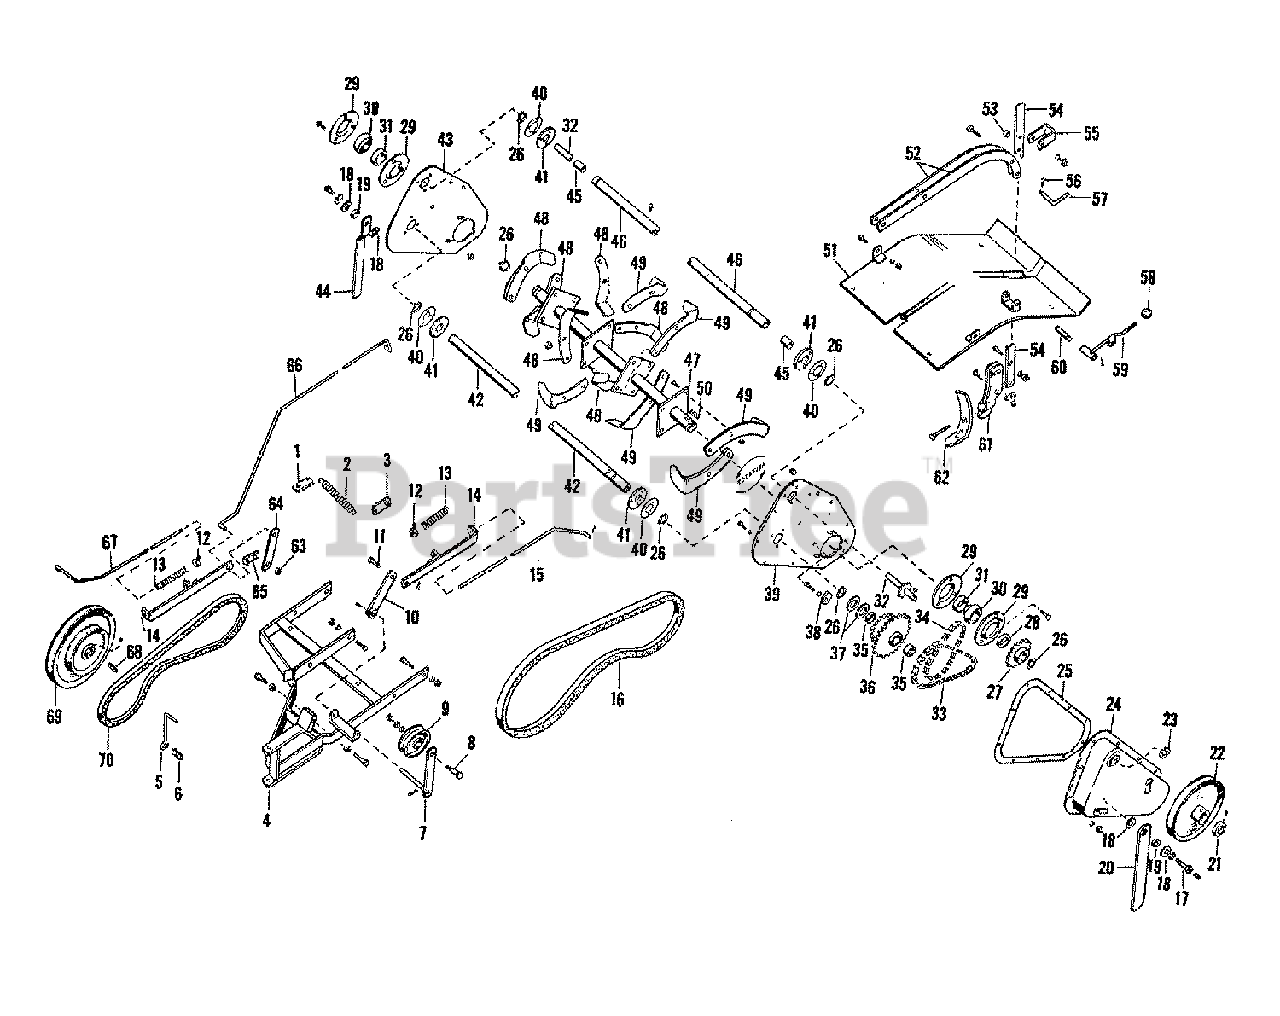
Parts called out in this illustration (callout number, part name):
1	SPRING, Holder, Upper
3	SPRING, Holder, Lower
4	FRAME ASSEMBLY
5	BELT, Stop
7	LEVER ASSEMBLY, Idler
8	IDLER PULLEY, Pin
9	PULLEY ASSEMBLY, Idler
10	LEVER ASSEMBLY, Idler Clutch
12	COLLAR, Set
14	GUIDE ASSEMBLY, Rod
15	IDLER CLUTCH, Rod
16	V" BELT, 58" Long`
20	STAND, L.H.
21	COLLAR
22	DRIVE, Sheave
24	GUARD ASSEMBLY
26	SNAP, Ring
27	DRIVEN, Sprocket
28	SPROCKET, Spacer
29	BEARING, Flange
30	BEARING, Flange
31	BEARING, Collar
32	DRIVE, Collar
33	DRIVE, Shaft Assembly
34	CHAIN, Rotor #50 - 27 1/2" Long
35	CHAIN, Countershaft #40-24" Long
37	SPROCKET ASEEMBLY
38	WASHER, Thrust
39	CHAIN, Tightener
40	PLATE, L.H. Side
42	CLAMP, Plate
43	COUNTER, Shaft
44	PLATE ASSEMBLY, R.H.
45	STAND, R.H.
47	DRIVE SHAFT, Housing
48	TINE SHAFT ASSEMBLY
49	TINE BLADE, L.H.
50	TINE BLADE, R.H.
52	DEFLECTOR ASSEMBLY
53	DEPTH GAUGE, Beam
55	DEPTH, Bar
56	GUIDE
57	CLIP SPRING
59	LEVER, Ball
60	LEVER ASSEMBLY, clutch
61	PIN, Lever Pivot
62	HOLDER ASSEMBLY, Tool
63	SHOE, Depth
65	LEVER, Lower Clutch
66	LEVER, Stop
67	IDLER CLUTCH, Rod
68	LOWER IDLER CLUTCH, Rod
70	SHEAVE ASSEMBLY, Transmission
